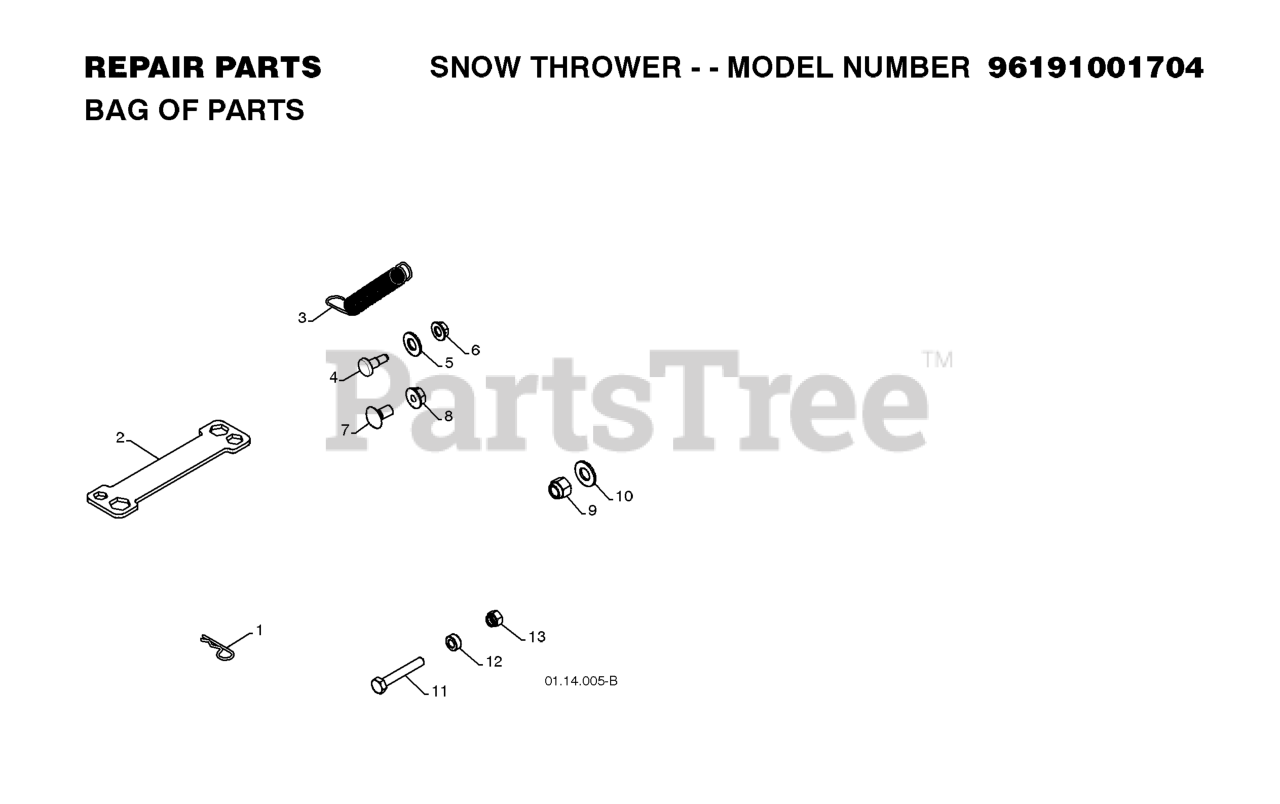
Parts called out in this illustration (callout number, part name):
1	SPRING RETAINER
2	RP WRENCH, SNOWTHROWER
3	SPRING.DEFLECTOR.REM.CHUTE
4	BOLT, SHOULDER
5	WASHER, NYLON FRICTION
6	NUT.HEX.FLANGE.1/4
7	BOLT
8	NUT.LOCK.5/16-18
9	NUT
10	WASHER
11	BOLT, SHEAR
12	SPACER.3943.SLEEVE.250X.47
13	LOCKNUT.NYLOC.1/4-20
